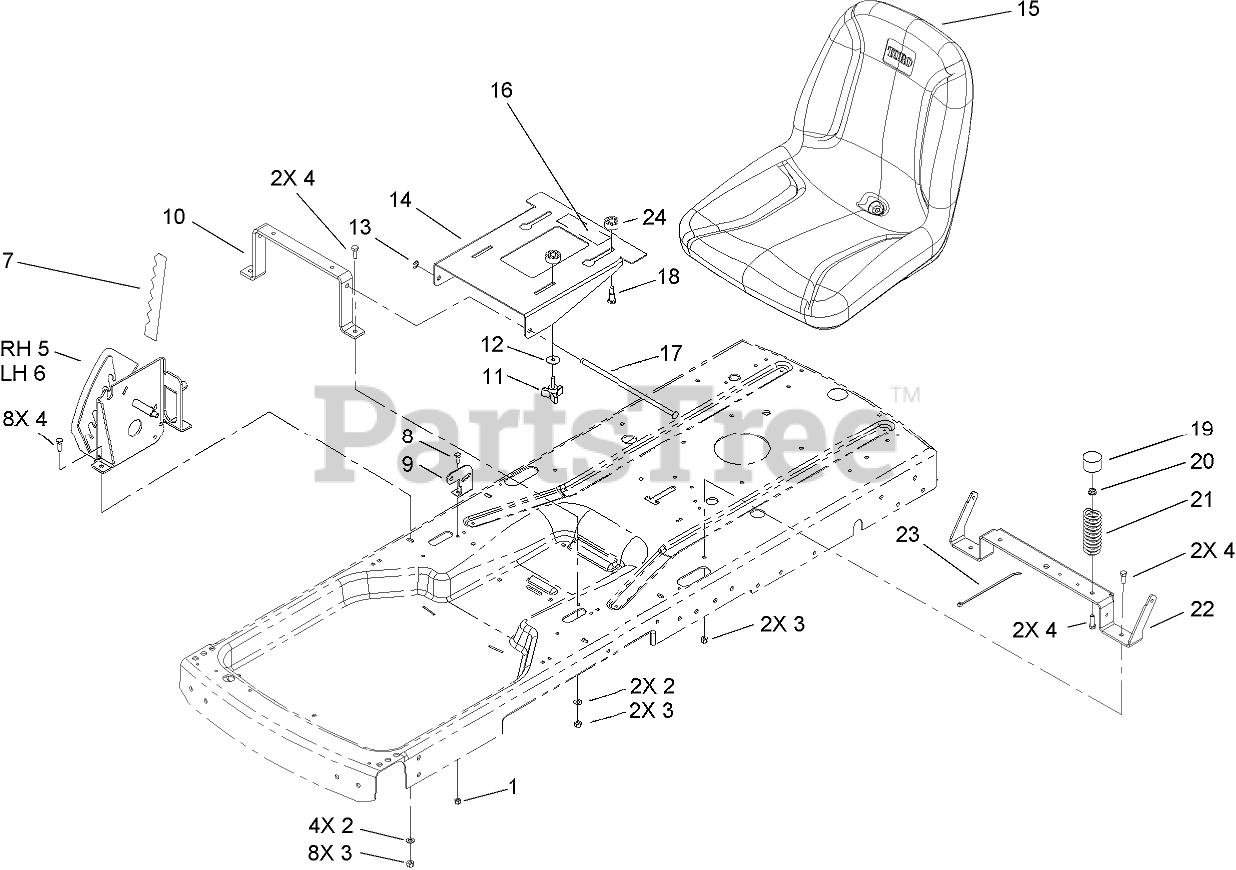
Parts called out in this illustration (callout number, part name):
1	NUT-LOCK, NI
2	WASHER-PLAIN
3	NUT-LOCK, NI
4	SCREW-HH
5	RH PLATE ASM
6	LH PLATE ASM
7	DECAL-HOC
8	SCREW-HH
9	BRACKET-BELLCRANK
10	BRACE-SEAT, FRONT
12	WASHER-PIVOT
13	E-RING
14	BRACKET-SEAT
15	SEAT-18 INCH
16	DECAL-SERVICE, CE
17	PIN-PIVOT
18	SCREW-SHOULDER
19	CAP-PROTECTOR
20	NUT-HF
21	SPRING-COMPRESSION
22	BRACE-SEAT, REAR
23	TIE-CABLE
24	SPACER-NYLON
